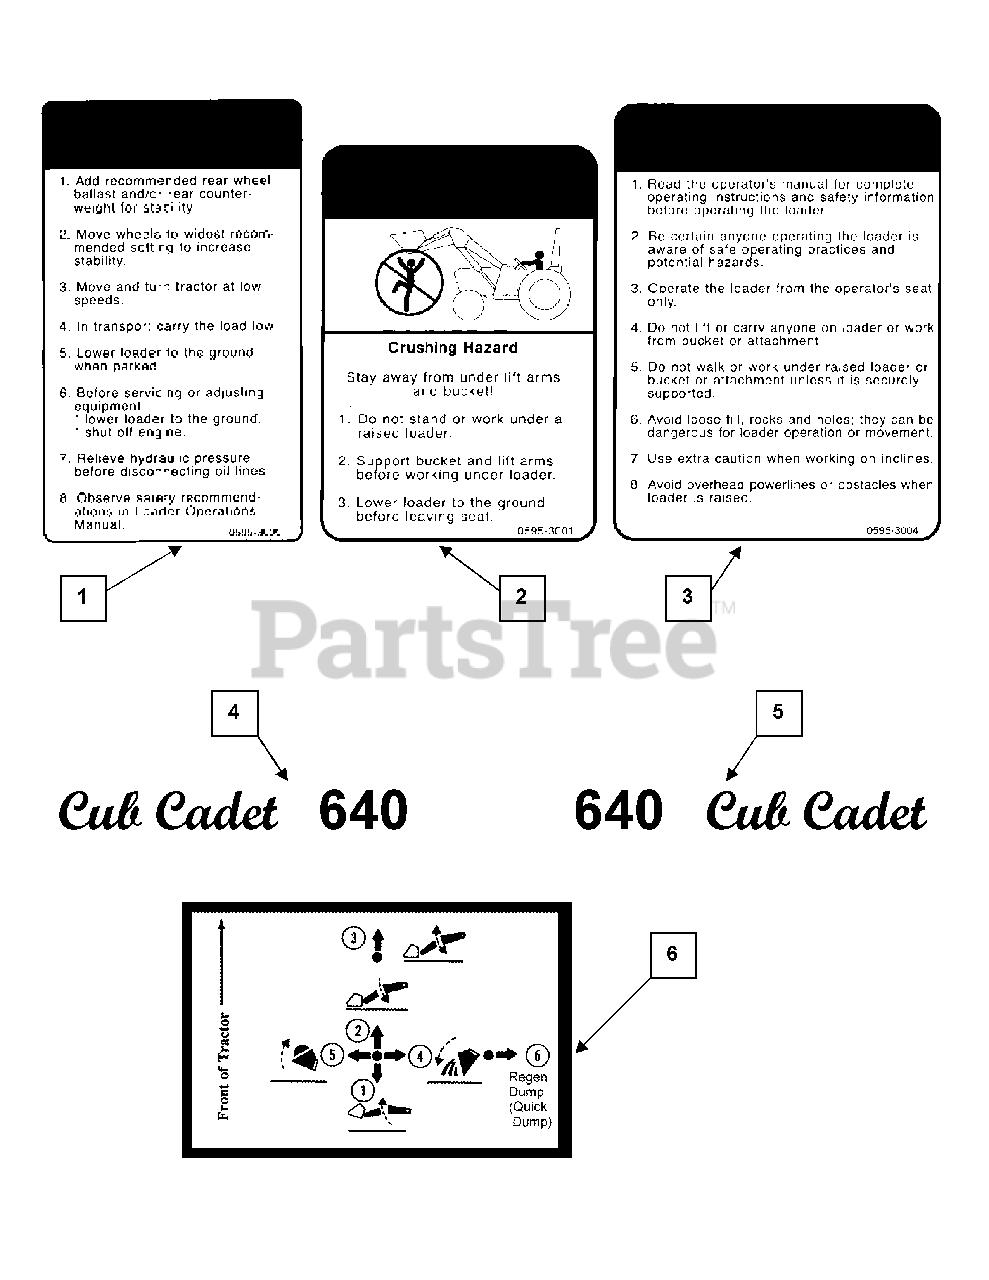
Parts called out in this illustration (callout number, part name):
1	Decal - Warning
2	Decal - Warning
3	Decal - Warning
4	Decal - Cub Cadet - 640 - RH
5	Decal - 640 - Cub Cadet - LH
6	Decal - Single Lever Control
